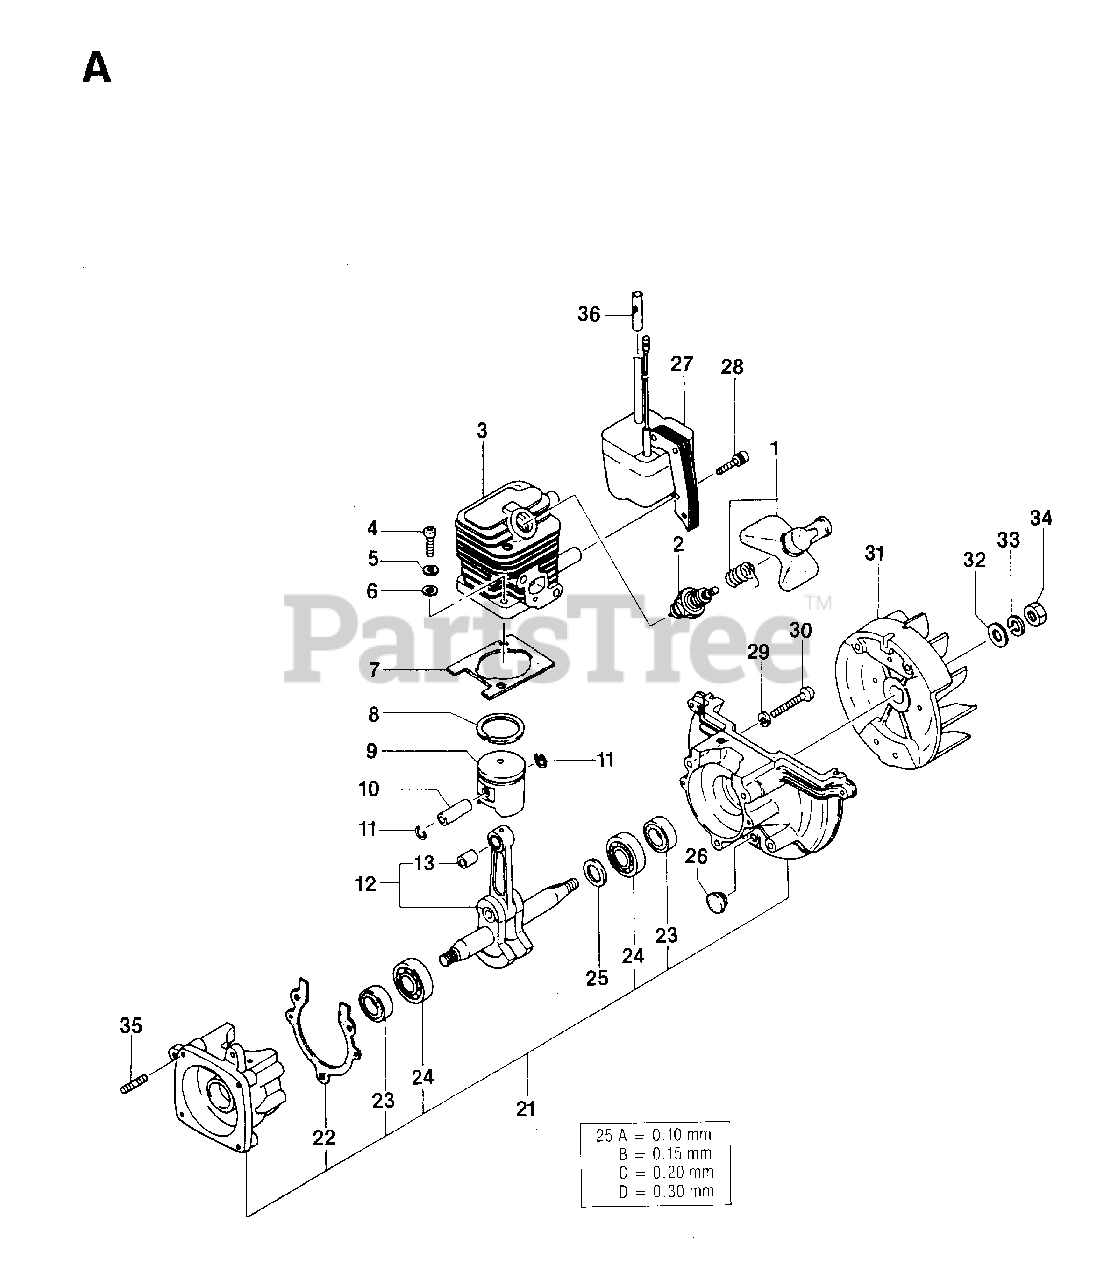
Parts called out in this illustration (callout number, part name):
2	SPARK PLUG CJ8 NLA
4	SCREW MC6S 5X20
5	SPRING WASHER
6	WASHER
29	SPRING WASHER
30	SCREW MC6S 5X30
32	WASHER BRB 8.4X17
33	SPRING WASHER
34	NUT
